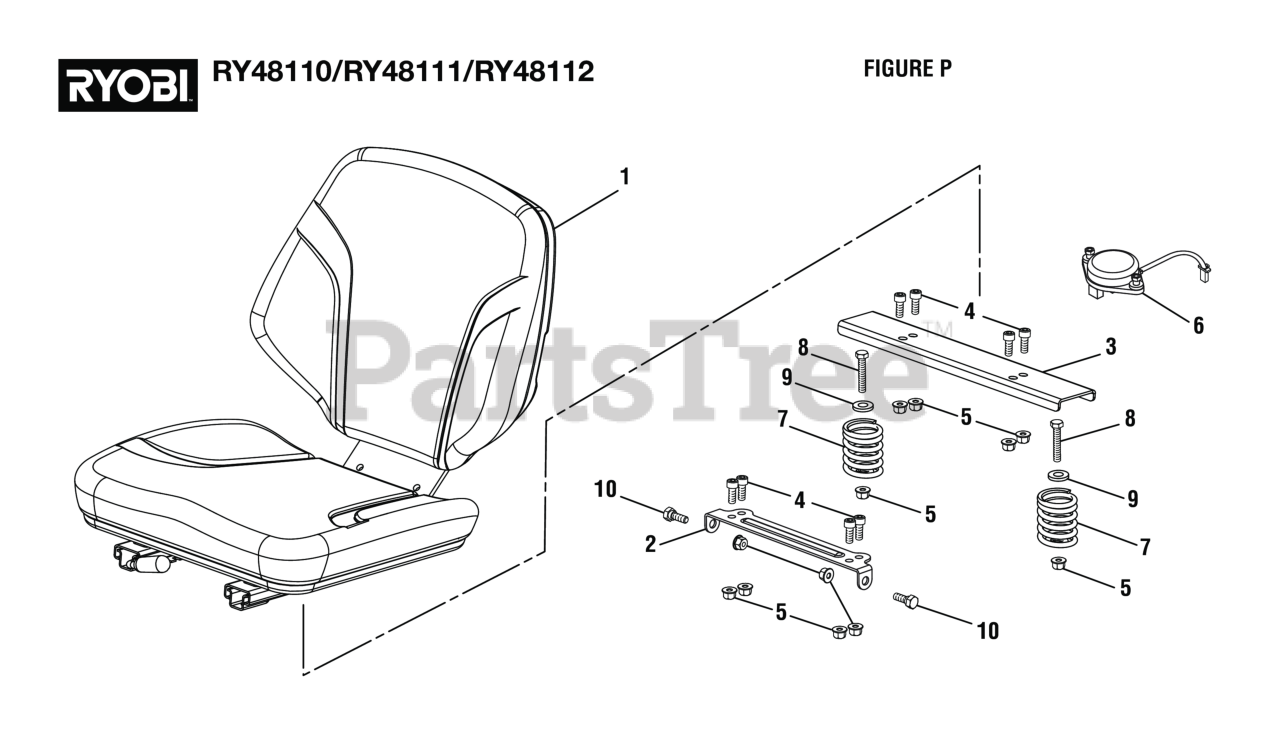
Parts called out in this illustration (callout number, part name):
2	Seat Base Plate
3	Seat Base Plate, Rear
4	Screw (M8 x 16 mm)
5	Flange Nut (M8) (For Drive Motor Controller V)
6	Seat Switch
7	Seat Spring
8	Shoulder Bolt (M8 x 45 mm, Hex Flange Hd.)
9	Washer (OD 24 x ID8.4 x 2t)
10	Shoulder Bolt (M8 x 20 mm)
